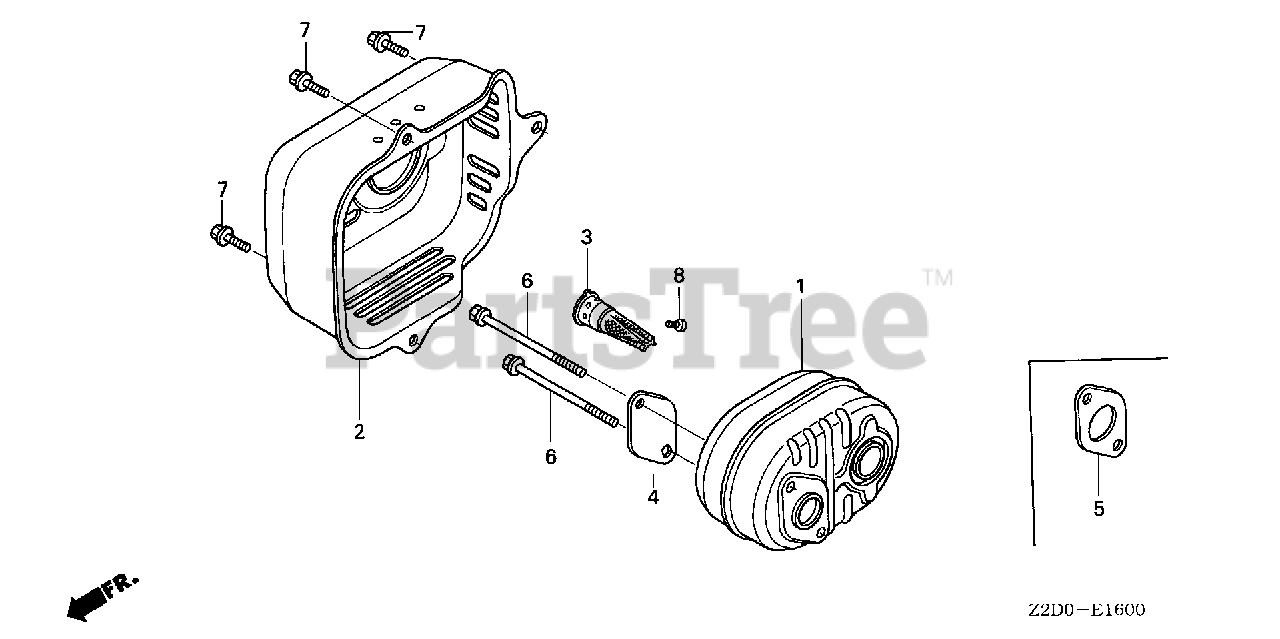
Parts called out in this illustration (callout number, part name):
1	MUFFLER
2	PROTECTOR, MUFFLER
3	ARRESTER, SPARK
4	PLATE, ARRESTER NUMBER
5	GASKET, MUFFLER
6	BOLT, FLANGE (6X79) (CT200)
7	BOLT, FLANGE (6X12) (CT200)
8	SCREW, TAPPING (4X6)
